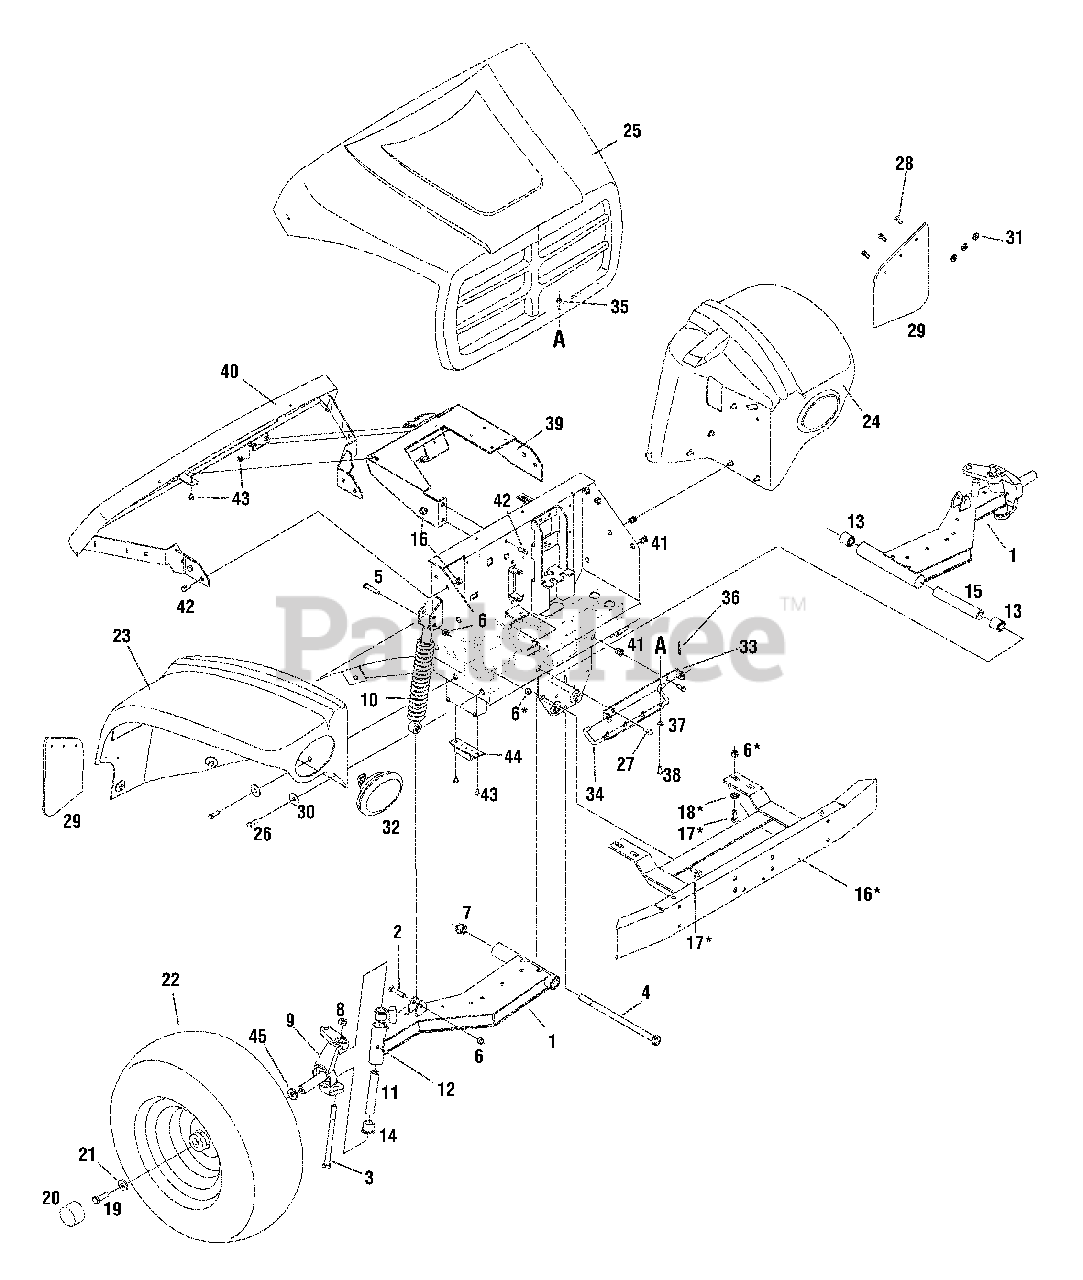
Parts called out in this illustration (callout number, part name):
1	Axle Assembly, Right-front
2	Hex Screw, 3/8-16 x 1.75
3	Hex Screw, 1/2-13 x 7.0, Gr5
4	Hex Screw, 5/8-11 x 11.13, Gr5
5	Hex Screw, 3/8-16 x 2.25
6	Nut, Hex Lock, Nylon, 3/8-16, Gr5
7	Nut, Hex Lock, Nylon, 5/8-11, Gr5
8	Nut, Hex Lock, 1/2-13
10	Shock Absorber, 2.9 Stroke
11	Tube, .875 x .50 x 4.75
12	Grease Fitting
13	Bearing, .63 ID x 1.19 OD
14	Bushing, Steering
15	Spacer, .645 ID x 1.063 OD
16	Flange Lock Nut, 3/8-16
17	Hex Screw, 3/8-16 x 1.0
18	Flat Washer,.406 x.875 x.059
19	Hex Screw, 1/2-13 x 1.50, Gr5
21	Flat Washer,.531 x 1.25 x.181
22	Rim, Front Wheel
23	Panel Assembly, Right Fender, Yellow
24	Panel Assembly, Left Fender, Yellow
25	Panel Assembly, Hood, Yellow
26	Hex Screw 5/16-18 x 1.00 Gr 5
27	Hex Screw, 5/16-18 x.75
28	Pop Rivet
30	Washer, Bell,.39 x 1.38 x.062
31	Flat Washer, .194 x .62 x .063
32	Head lamp Assembly
35	Nut, Hex Lock, 1/4-20
36	Cotter Pin, Internal, 1.42
37	Washer, Flat,.271 x.63 x.065
38	Hex Screw, 1/4-20 x.75
41	Insert Nut, 5/16-18
42	Hex Screw, 3/8-16 x.75
43	Screw, Self-tapping, 1/4-20 x.5
44	Suspension Bumper
45	Flat Washer, 1.030 x 1.625 x.090
